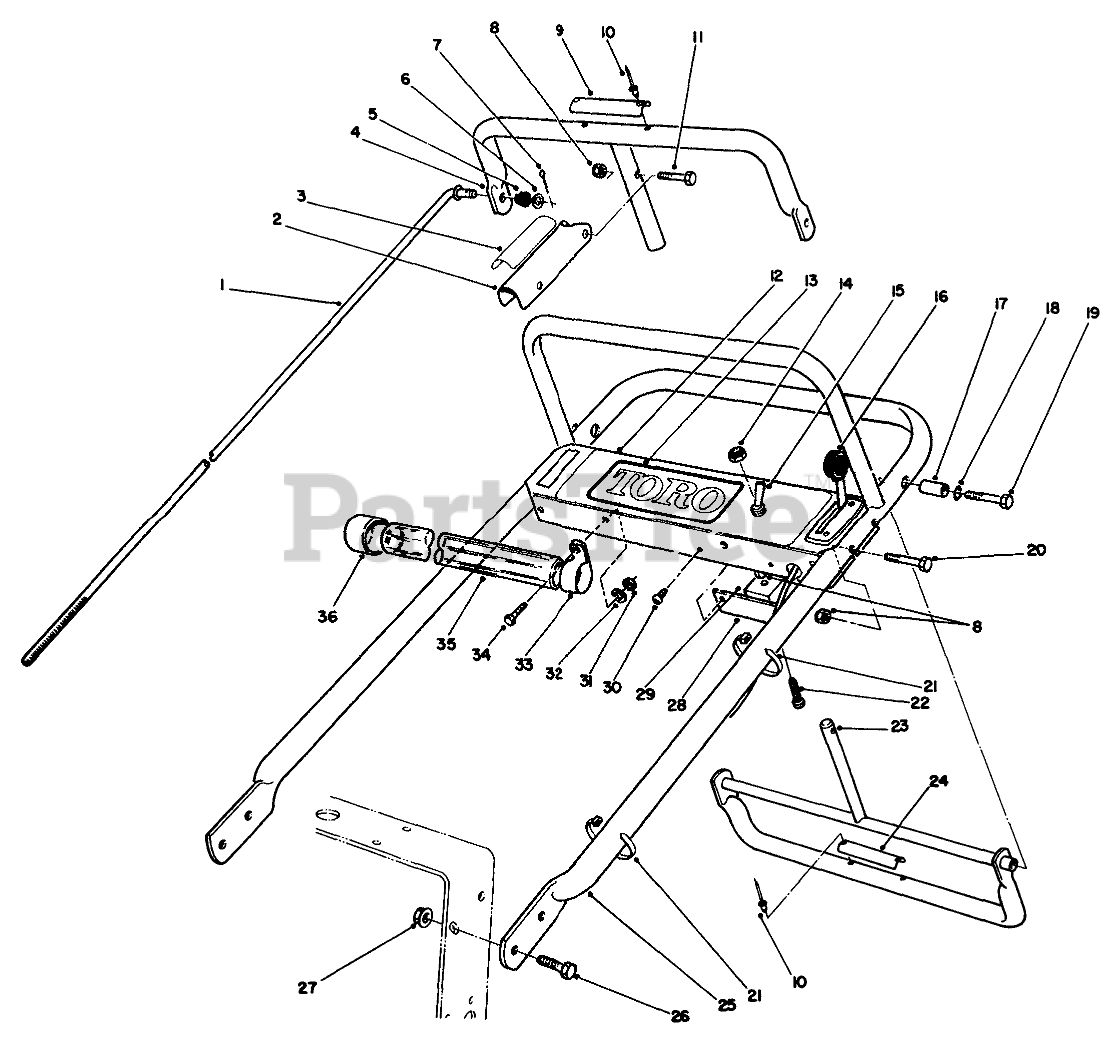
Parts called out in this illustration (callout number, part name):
1	ROD-CONTROL
2	Lever-Parking Brake
3	DECAL-LEVER, PARKING
4	Bar-Control
5	GROMMET-RUBBER
6	WASHER-FLAT
7	PIN-COTTER
8	NUT-LOCK, NI
9	DECAL-CONTROL BAR
10	RIVET-BLIND
11	SCREW-SHH
12	Panel-Control
13	JLO PANEL DECAL
14	NUT
15	Switch
16	THROTTLE CONTROL JLO
17	PIVOT-SPACER
18	WASHER-LOCK
19	SCREW-HH
20	SCREW-SHH
21	TIE-CABLE
22	SCREW-HWH
23	Control-Pivot
24	DECAL-REVERSE HANDLE
25	HANDLE-UPPER
26	SCREW-HHF
27	NUT-HF
28	PANEL-BOTTOM
29	RECTIFIER-BRIDGE
30	SCREW-HWHTF
31	NUT-LOCK, NI
32	WASHER-FLAT
33	CLAMP-R
34	SCREW-HH
36	CAP-END
